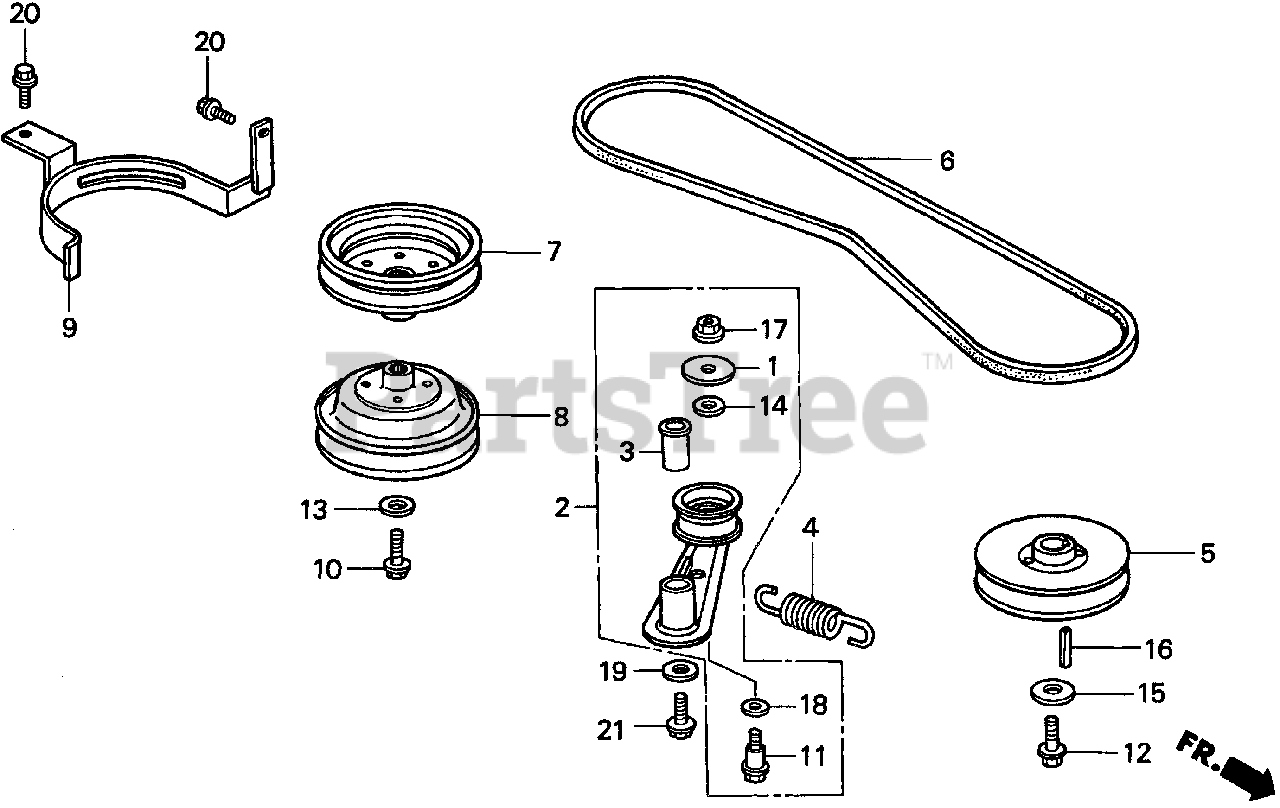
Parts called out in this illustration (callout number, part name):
1	GUARD, TENSION ROLLER
2	ARM ASSY., TENSIONER
3	BUSH (15X19X39.5)
4	SPRING, PRIMARY BELT TENSION
5	PULLEY, ENGINE (120MM)
6	V-BELT, PRIMARY (SB-51)
7	PULLEY, TRANSMISSION (ENGINE)
8	PULLEY, TRANSMISSION (DECK)
9	STOPPER, BELT
10	BOLT, FLANGE (8X20)
11	BOLT, SPECIAL (6X23)
12	BOLT, FLANGE (7/16"X28)
13	WASHER, SPECIAL (28X8.5X4.0)
14	WASHER, THRUST (8MM)
15	WASHER, PLAIN (12MM)
16	KEY (6.3X6.3X30)
17	NUT, FLANGE (6MM)
18	WASHER, PLAIN (6MM)
19	WASHER, PLAIN (10MM)
20	BOLT, FLANGE (6X12)
21	BOLT, FLANGE (10X20)
